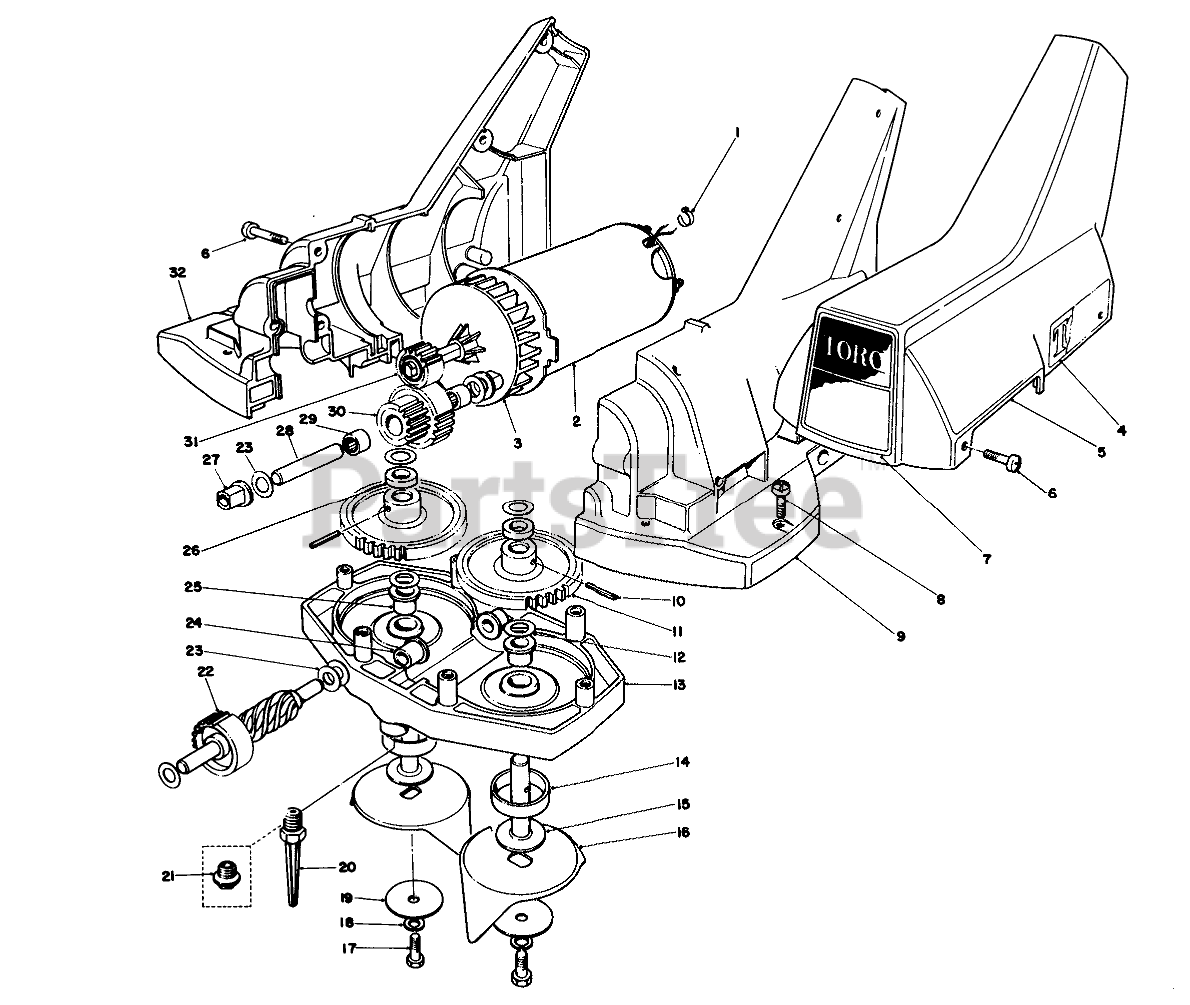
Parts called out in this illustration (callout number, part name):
1	TIE-CABLE
2	Motor (Incl. Ref. #3 & 31)
4	DECAL - TORO
5	Cover
7	Decal
8	#10-32 PHILLIPS TF SC
9	Upper Case L.H. (Incl. Ref. #25)
10	PIN-GROOVED
11	HELICAL GEAR
12	THRUST RACE
13	Lower Case (Incl. Ref. #25)
14	SPACER
15	Tine Shaft
16	Tine Cup
17	1/4-20 X 5/8 CAPSCREW
18	WASHER-LOCK
19	WASHER-FLAT
20	STABILIZER SPIKE
22	Worm Shaft w/Gear
23	THRUST WASHER
24	Bushing
25	BUSHING-FLANGE
26	COLLAR
27	Sleeve
28	Idler Shaft
29	Bearing
30	CLUSTER GEAR
31	Driver Gear
32	Upper Case R.H. (Incl. Ref. #25)
